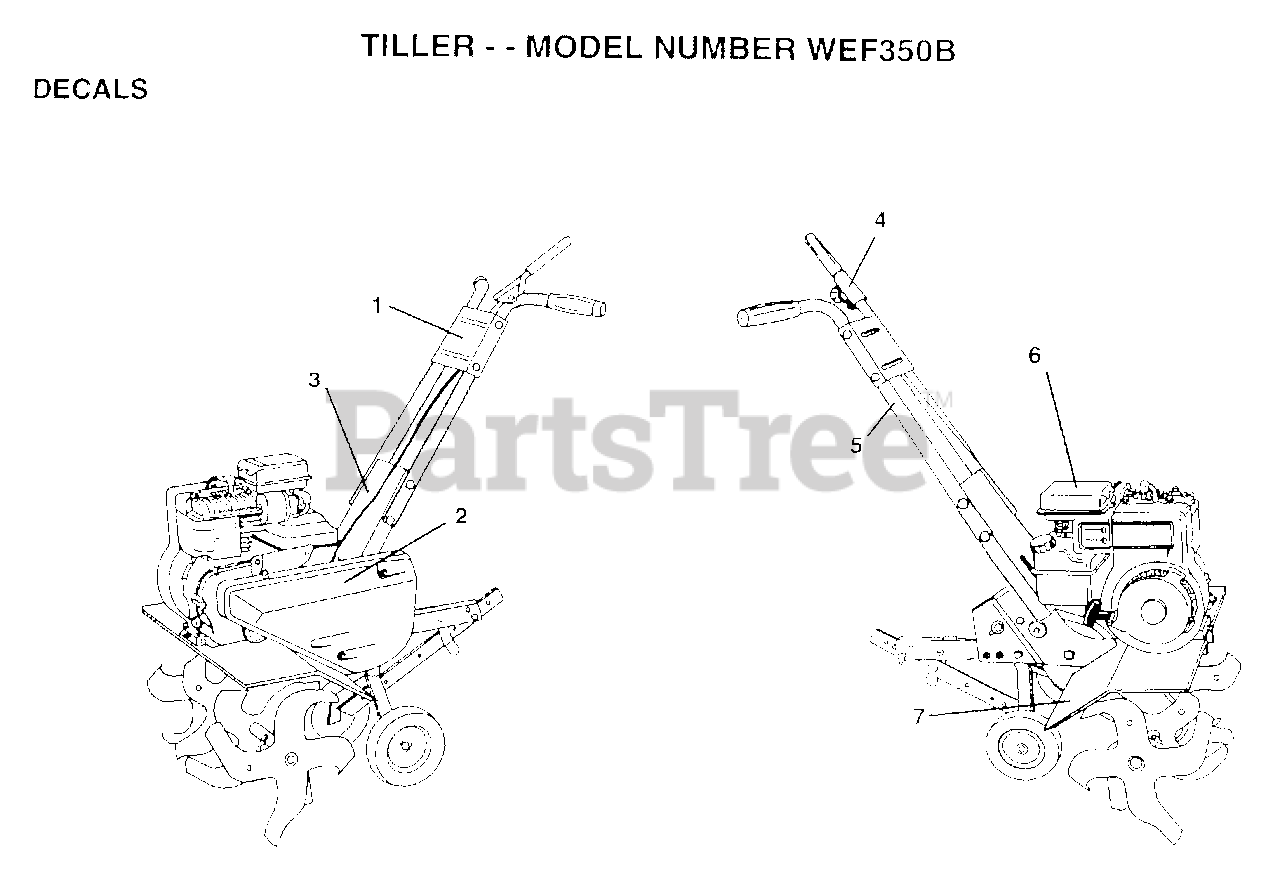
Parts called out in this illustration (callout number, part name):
2	DECAL.BELT.GUARD
3	DECAL.LOWER.PANEL
4	DECAL TI
5	DECAL TI
6	DECAL TI
